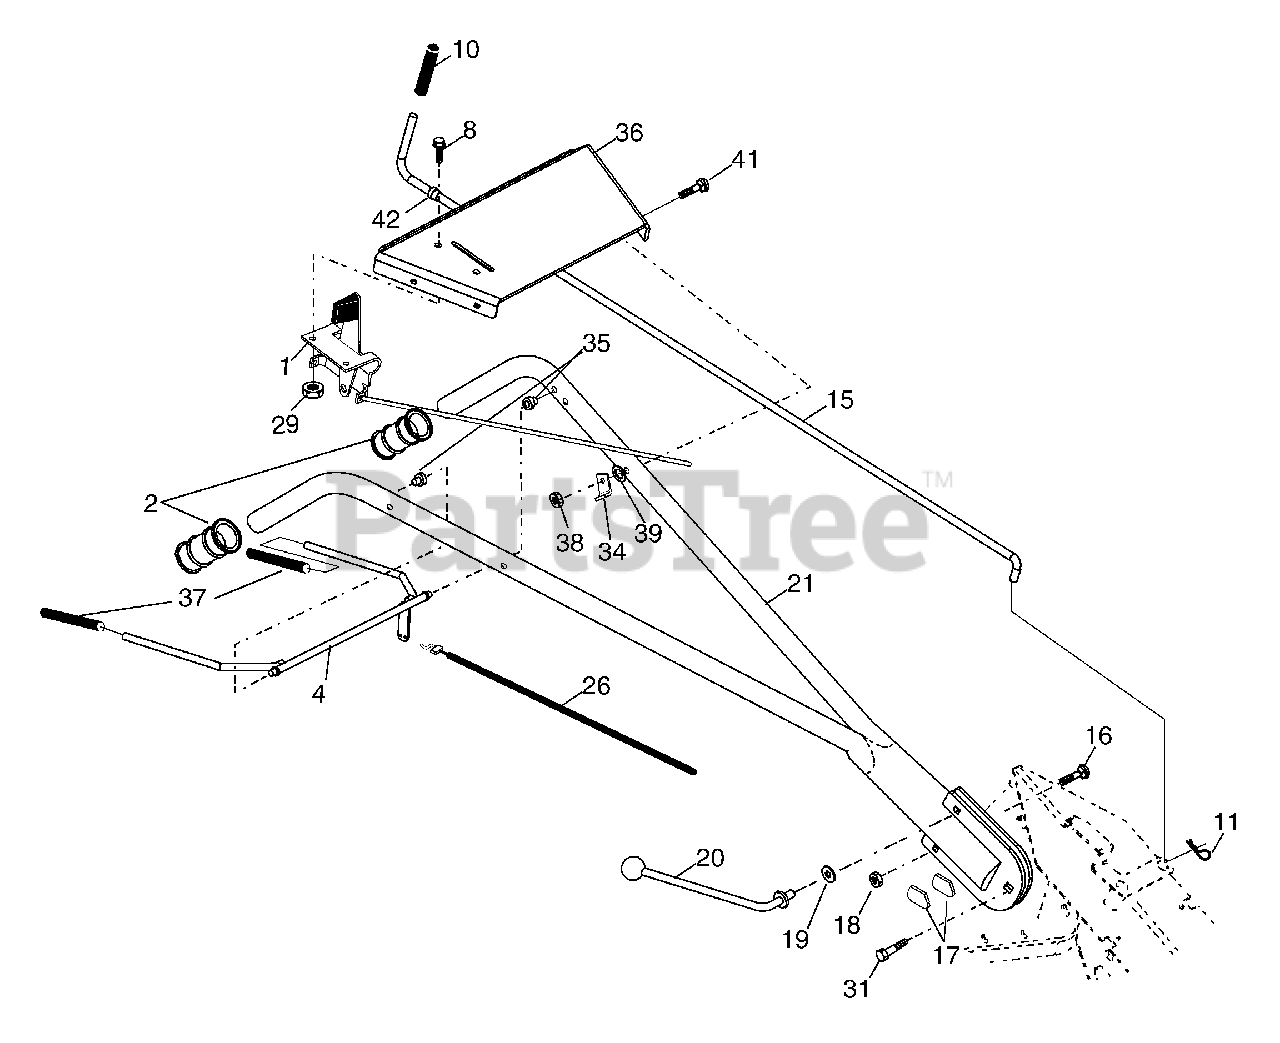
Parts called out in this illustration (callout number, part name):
1	Control, Throttle
2	Grip, Handle
4	Bar, Control
8	Screw, Pan Hd. #10-24
10	Grip, Handle
11	Clip, Hairpin
15	Rod, Shift
16	Bolt, Carriage 3/8-16 x 1 Gr. 5
17	Lock, Handle
18	Nut Crownlock 3/8-16 Unc
19	Washer 13/32 x 1 x 11 Ga.
20	Lever, Lock, Handle
26	Cable, Clutch
29	Nut, Keps #10-24 Unc
31	Bolt, Pivot
34	Bracket, Clutch Cable
35	Grommet, Handle
36	Bracket, Handle
37	Grip, Bar Control
38	Locknut 5/16-18
39	Washer, Lock 5/16
41	Bolt, Carriage 5/16-18 x 1-3/4
42	Bushing, Snap
